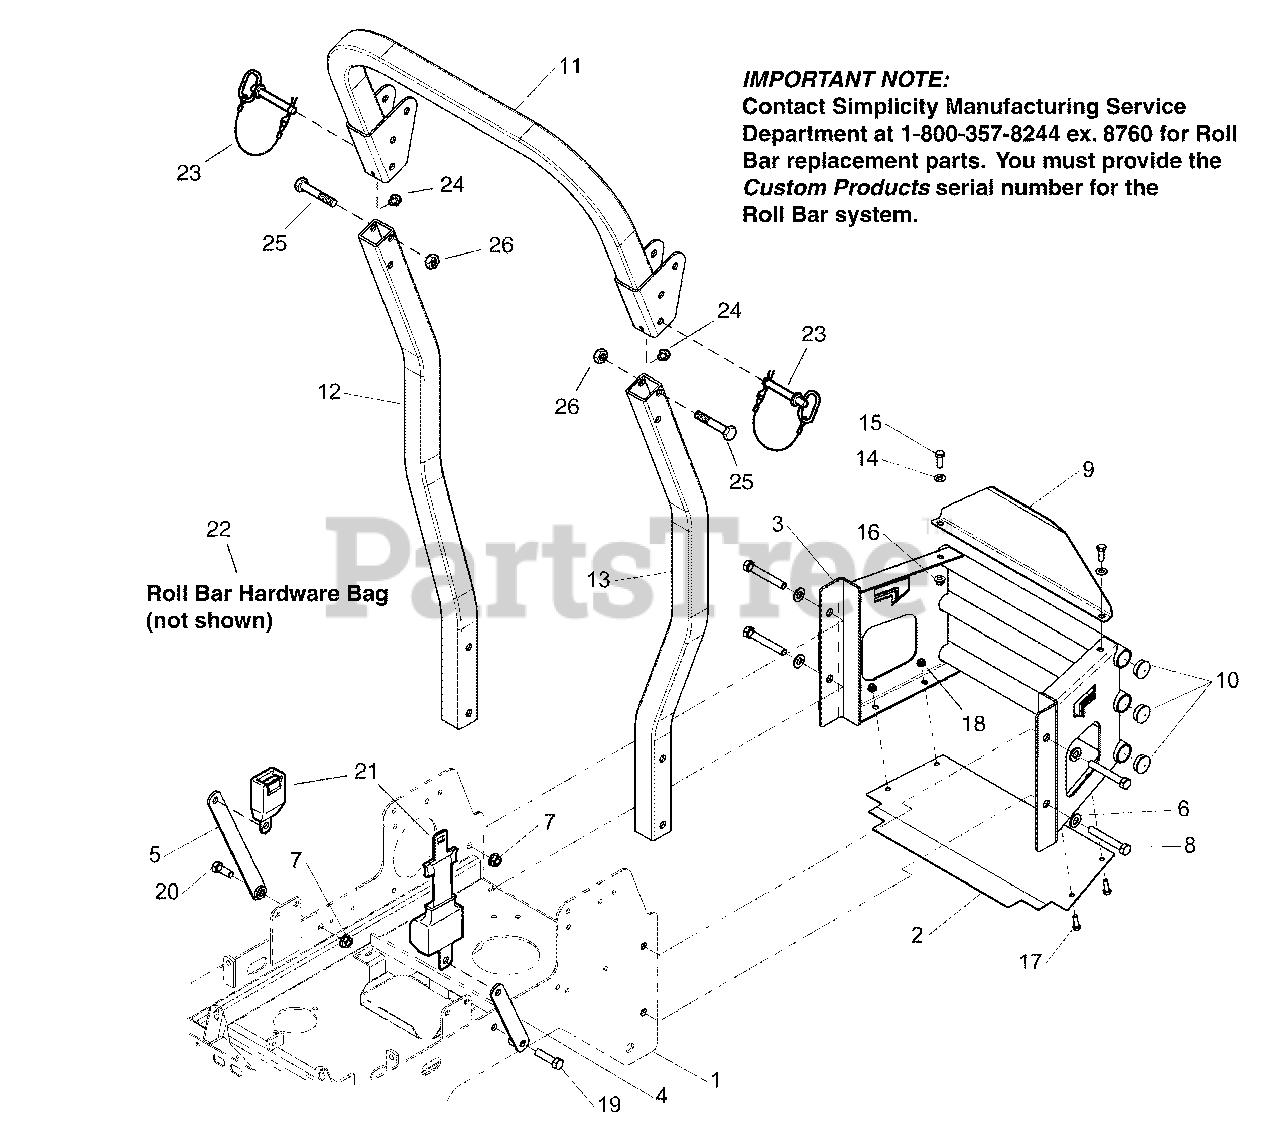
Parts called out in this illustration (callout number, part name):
1	MAIN FRAME
2	PLATE, HEAT SHIELD
3	WELD, SEAT BELT ANCHOR - LH
4	MOUNT, SEAT BELT - RH - BLK
5	WELD, BUMPER - CITATION
6	WASHER, 1/2" SAE
7	NUT, 1/2-13 HEX NYLOCK FLANGE
8	BOLT, 1/2-13 X 3-1/2" GD5
9	PLUG, PANEL, 1.25 BLACK
10	ROLL BAR TOP LOOP
11	ROLL BAR POST, RH
12	ROLL BAR POST, LH
13	BOLT, 5/16-18 X 1" GD5
14	NUT, 5/16-18 HEX NYLOCK FLANGE
15	BOLT, 1/2-13 X 1-3/4" GD5
16	BOLT, 1/2-13 X 2-1/4" GD5
17	SEAT BELT ASSEMBLY, Standard
17	SEAT BELT ASSEMBLY, Extra Long
18	ROLL BAR HARDWARE BAG
19	PIN, Hitch, .50 x 3.25 W/ Lanyard
20	RUBBER BUMPER
21	* BOLT
22	* NUT
23	PIN, HITCH, BLACK W/ PLASTIC LANYARD
24	RUBBER BUMPER
25	*BOLT
26	*NUT
28	ROPS (Call 1-800-933-6175 x708 if replacing a ROPS)
